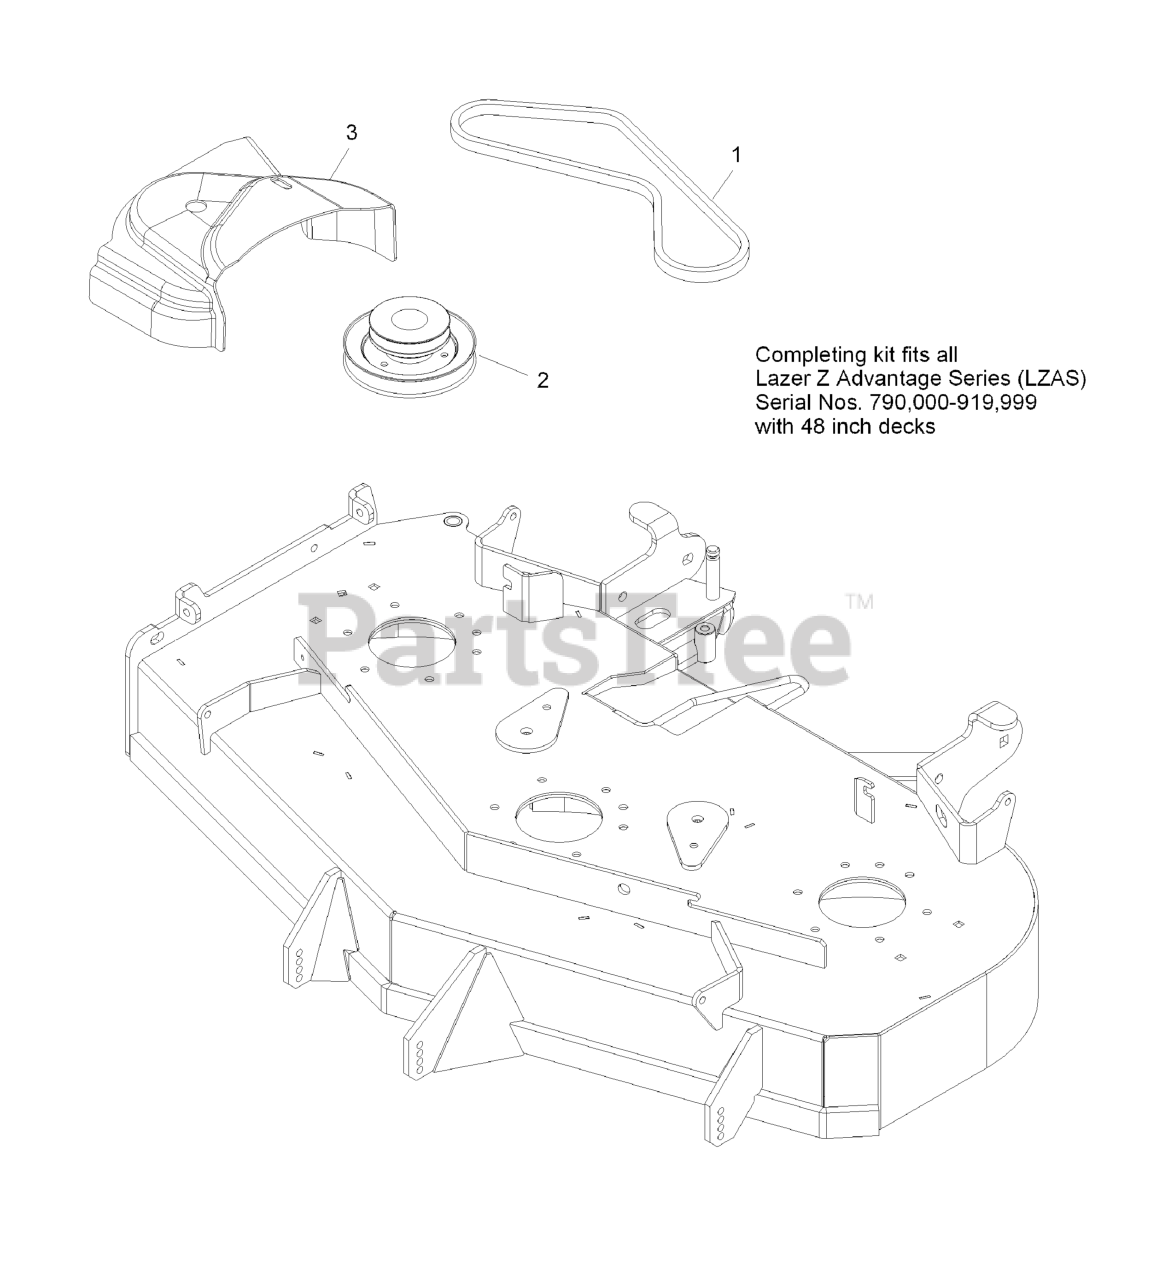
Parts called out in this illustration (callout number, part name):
1	BELT-BLOWER
2	JACKSHAFT,UV DRIVE 484
3	COVER,BELT UV 48
